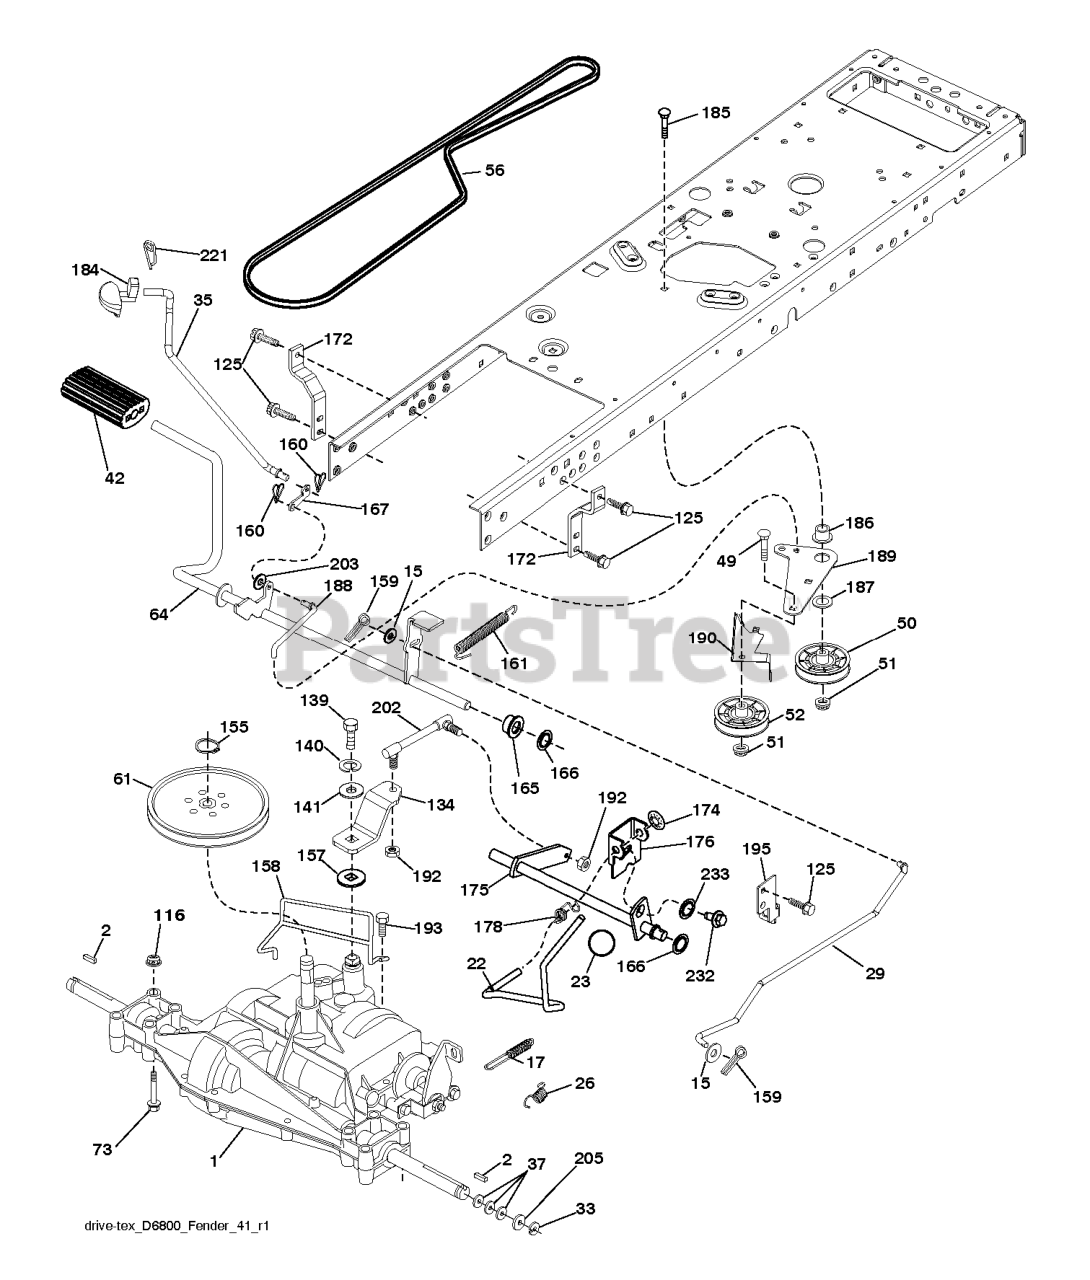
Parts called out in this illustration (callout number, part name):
2	SQUARE KEY
15	WASHER
17	SPRING.BRAKE.PEERLESS.TEX
22	ROD.SHIFT.FENDER.TLT.2006
23	KNOB.DUCKHEAD.1/2
26	SPRING.BRAKE.RTN.GR.DR
29	ROD.BRAKE.PEERLESS
35	ROD.CNTRL.PARK.PREDATOR.LT.TEX
42	PEDAL COVER T
50	IDLER.FLAT.910.OFFSET
51	NUT LOCK FLG 3/8-16 UNC
52	IDLER.V-GROOVE.910.OFFSET
61	PULLEY TRANS
64	SHAFT.ASM.PEDAL.BRAKE.
73	BOLT HEX 5/16-18 GR 5
116	NUT LOCK HEX FLANGE 5/16-18
125	SCREW
134	ARM.SHIFT.
139	BOLT 1/4-28X3/4
140	LOCKWASHER
155	RETAINING RING LT
157	WASH-SHFT PLT LT
158	KEEPER.PMS.18/20.D4365
159	COTTER PIN
160	RETAINER CLIP
161	SPRING, RETURN LT
165	BUSHING.SHAFT.BRAKE.HAND
166	NUT.PUSH.625.2006
167	LATCH.BRAKE.SPRING
172	STRAP.TRQ.LH.GEAR.DRIV
174	NUT.PUSH.500.2006
175	SHAFT.ASM.SHIFT.
176	ARM.CLEVIS.ROD.SHIFT
178	SPRING.SHIFT.GT2006
184	HANDLE PARKING BRAKE
186	SPACER.RETAINER
187	WASHER 12/32X2X10GA
188	RP.LINK.CLUTCH.GROUND.DRIVE
189	BELLCRANK.GROUND.DRIVE.TEX.
190	KEEPER.BELLCRANK.DRIVE
192	NUT LOCK CENTER 1/4 -28 FNTHD
193	SCREW 5/16"
195	BRKT.ROD.BRAKE.PEERLES
202	LINK.TRANSAXLE.D6800.18/20"TEX
203	WASHER
221	RETAINER.SPRING.CLIP.H
232	BOLT FIN HEX 7/16-14 X 1
233	WASHER SERRATED
